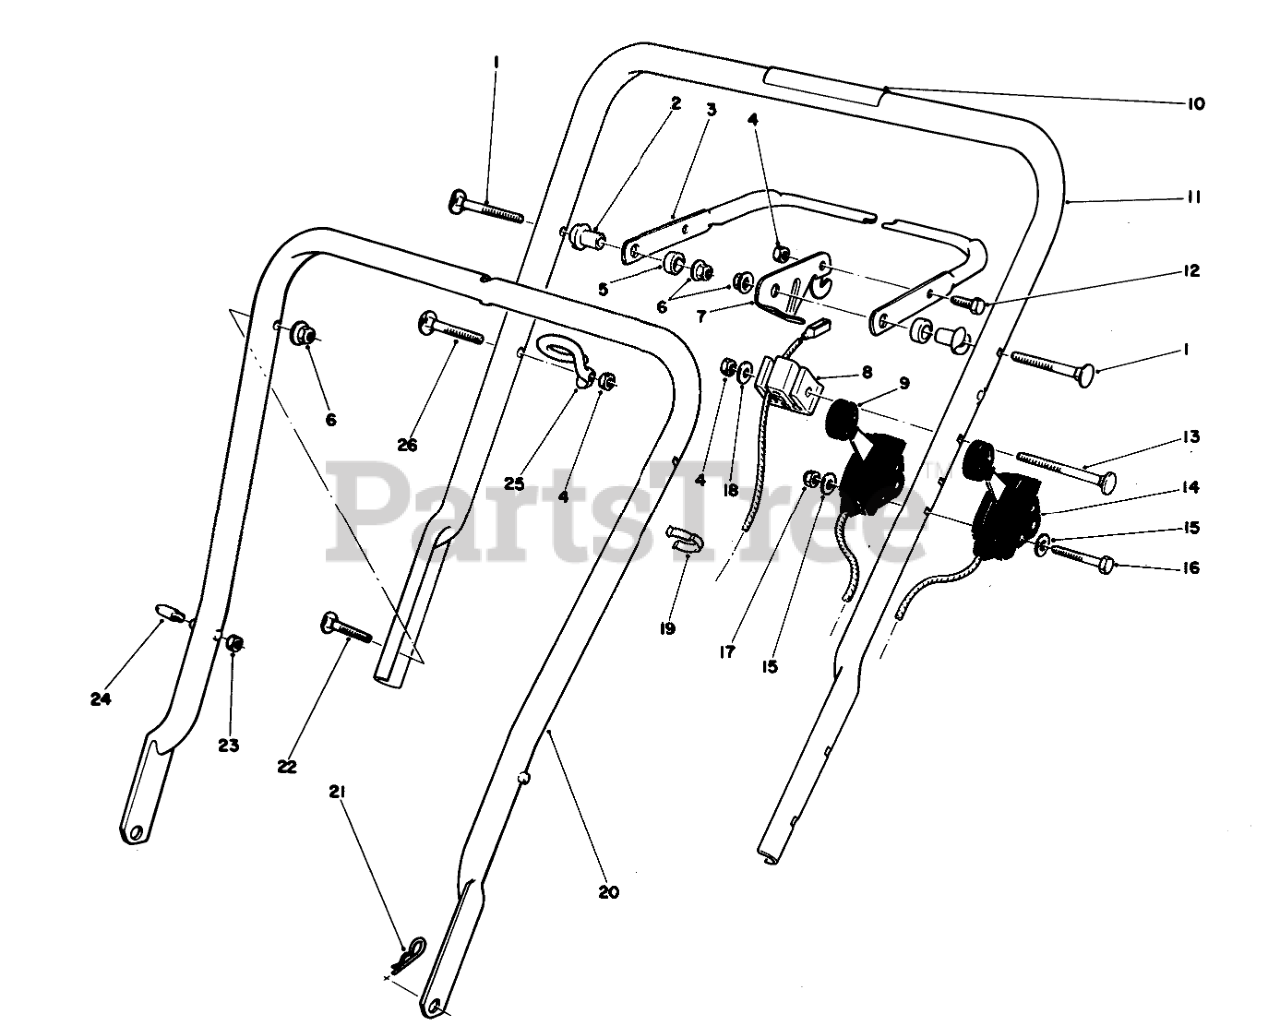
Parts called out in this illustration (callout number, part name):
1	5/16-18 X 2 HNDLE SCREW
2	SPACER-SUPPORT
3	Bar-Control
4	NUT-LOCK, NI
5	SPACER-NYLON
6	NUT-LOCK, NI
7	LEVER-CONTROL
8	SUPPORT-CABLE
9	THROTTLE CONT-SERVICE
10	WARNING DECAL
11	Handle-Upper (Incl. Ref. #10)
12	SCREW-HH
13	HANDLE SCREW
14	TRACTION CONTROL
15	WASHER-FLAT
16	SCREW-SHH
17	NUT-LOCK, NI
18	WASHER-FLAT
19	BOWDEN CLIP
20	LOWER HANDLE ASM
21	PIN-COTTER, HAIR
22	SCREW
23	NUT-LOCK, NI
24	HANDLE PIN
25	Guide
26	HANDLE SCREW
